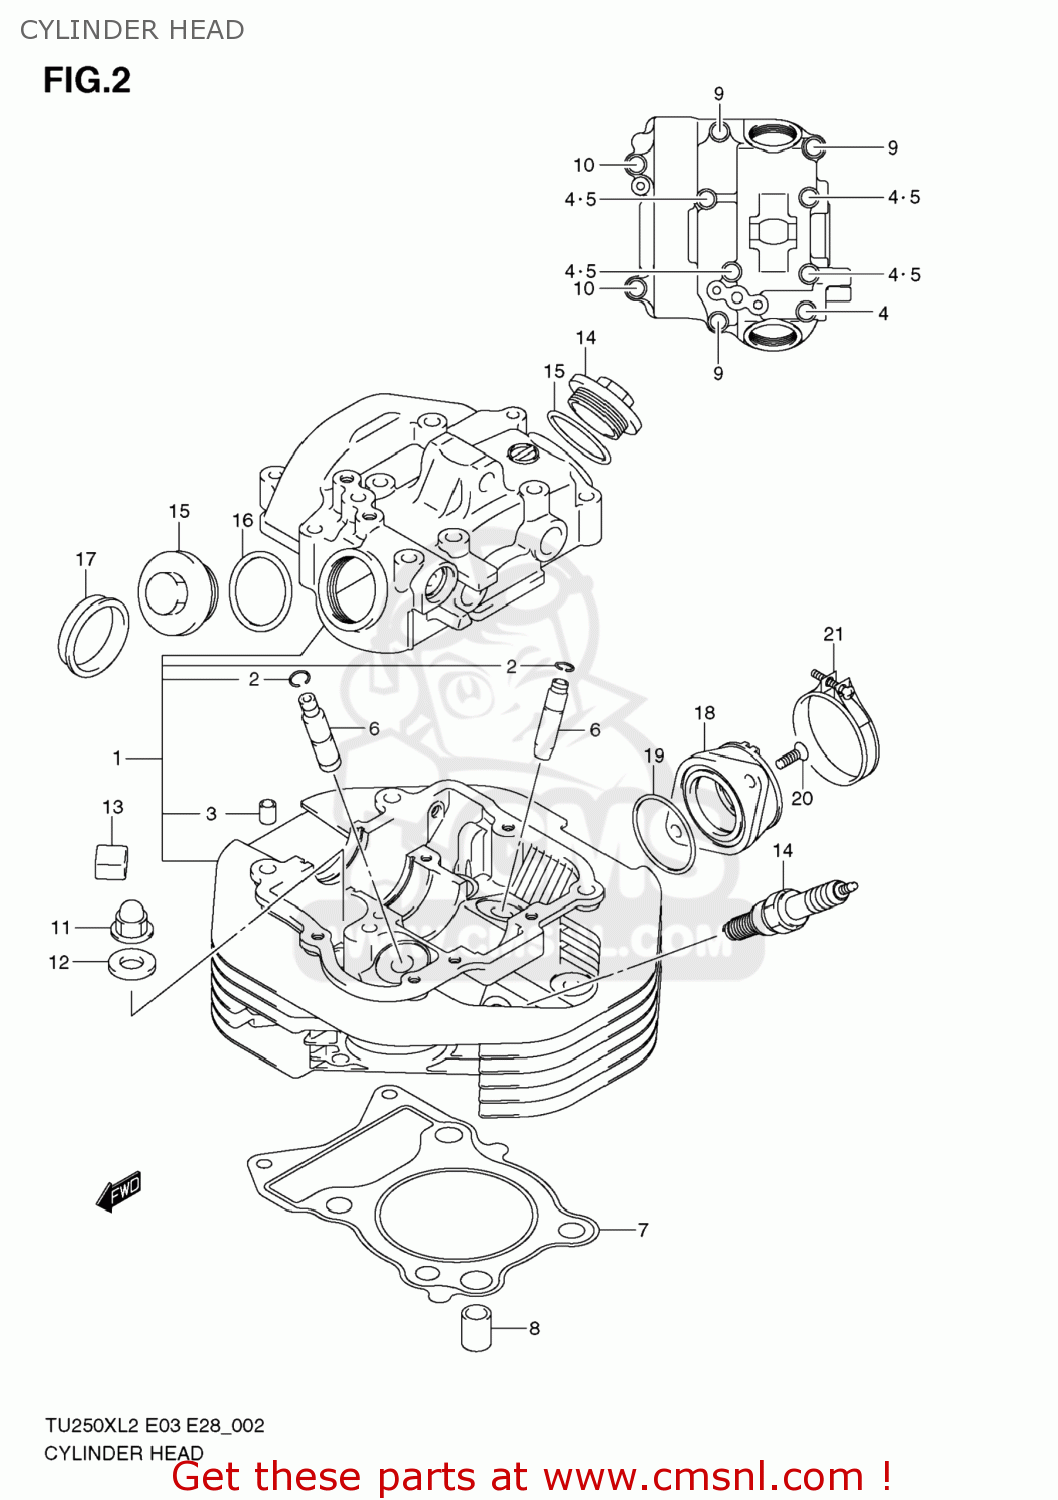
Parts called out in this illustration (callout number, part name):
1	HEAD ASSY,CYLINDER
2	RING,SNAP
3	PIN(6.2X8X11)
4	BOLT(6X60)
5	GASKET(5.8X13X1.2) (NAS)
6	GUIDE,VALVE
7	GASKET,CYLINDER HEAD (NAS)
8	PIN
9	BOLT
10	NUT
11	NUT
12	GASKET(10.5X22X2) (NAS)
13	PAD,CYLINDER HEAD
14	PLUG,SPARK(DR8EA)
15	CAP,INSPECTION
16	O RING(D:3,ID:29.5)
17	PLUG
18	PIPE,INTAKE
19	O RING(D:2.4,ID:39.7)
20	SCREW
21	CLAMP
